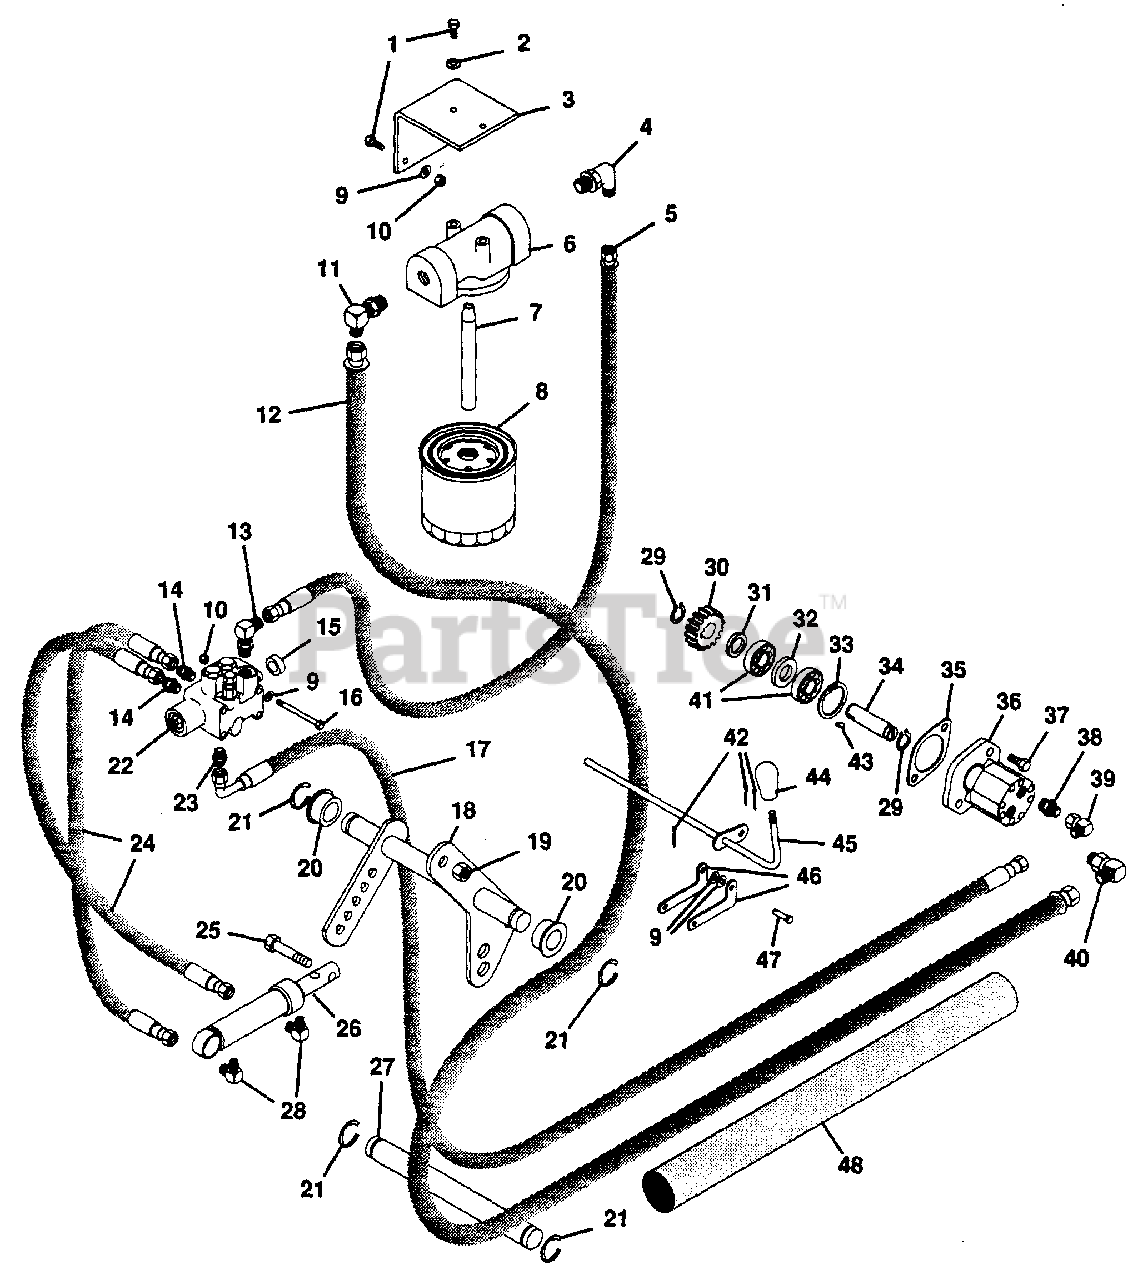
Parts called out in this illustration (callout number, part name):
1	BOLT, HEX 1/4-20X.750
2	WASHER, LOCK 1/4 REG.
3	BRACKET, OIL FILTER MTG.
4	ADAPTOR, PH #2503-8-6
5	HOSE, HYDRAULIC VALVE TO TANK
6	BASE, FILTER
7	TUBE, OIL PICK-UP
8	FILTER, ELEMENT
9	WASHER, FLAT .281X.625X.065
10	NUT, LOCK 1/4-20
11	ADAPTOR, PH #2503-8-8
12	HOSE, HYDRAULIC(FILTER TO PUMP)
13	ADAPTOR(P-H #2503-6-6)
14	ADAPTOR(P-H #0503-4-4)
15	BUSHING, ST. .700X1.00X3.00 STL.
16	BOLT, HEX 1/4-20X2.75
17	HOSE, HYDRAULIC(PUMP TO VALVE)
18	WELDMENT, LIFT LEVER SHAFT
19	NUT, LOCK 1/2-13
20	BUSHING, PIVOT
21	E-RING, 1.000 SHAFT
22	VALVE, HYDRAULIC
23	ADAPTOR, PH #0503-6-6
24	HOSE, HYDRAULIC 14.5
25	BOLT, HEX 1/2-13X2.00
26	CYLINDER, HYDRAULIC
27	SHAFT, HYDRAULIC CYLINDER
28	ADAPTOR(P-H #2503-4-4)
29	RING, RETAINING .594 SHAFT
30	GEAR, HYDRAULIC PUMP
31	SPACER, .620X.750X.276
32	SPACER, .620X.750X.364
33	RING, RETAINING 1.378 BORE
34	SHAFT, HYDRAULIC PUMP
35	GASKET, COVER PLATE
36	PUMP, HYDRAULIC
37	BOLT, HEX 3/8-16X.75
38	ADAPTOR
39	ADAPTOR(P-H #3903-6-6)
40	ADAPTOR(P-H #2503-10-B)
41	BEARING, BALL .590X1.378X.433
42	PIN, COTTER .094X.75
43	KEY, WOODRUFF .125X.375 HARD
44	KNOB, PTO
45	WELDMENT, HYDRAULIC CONTROL ROD
46	ROD, HYDRAULIC CONTROL
47	PIN, CLEVIS
48	SLEEVE
